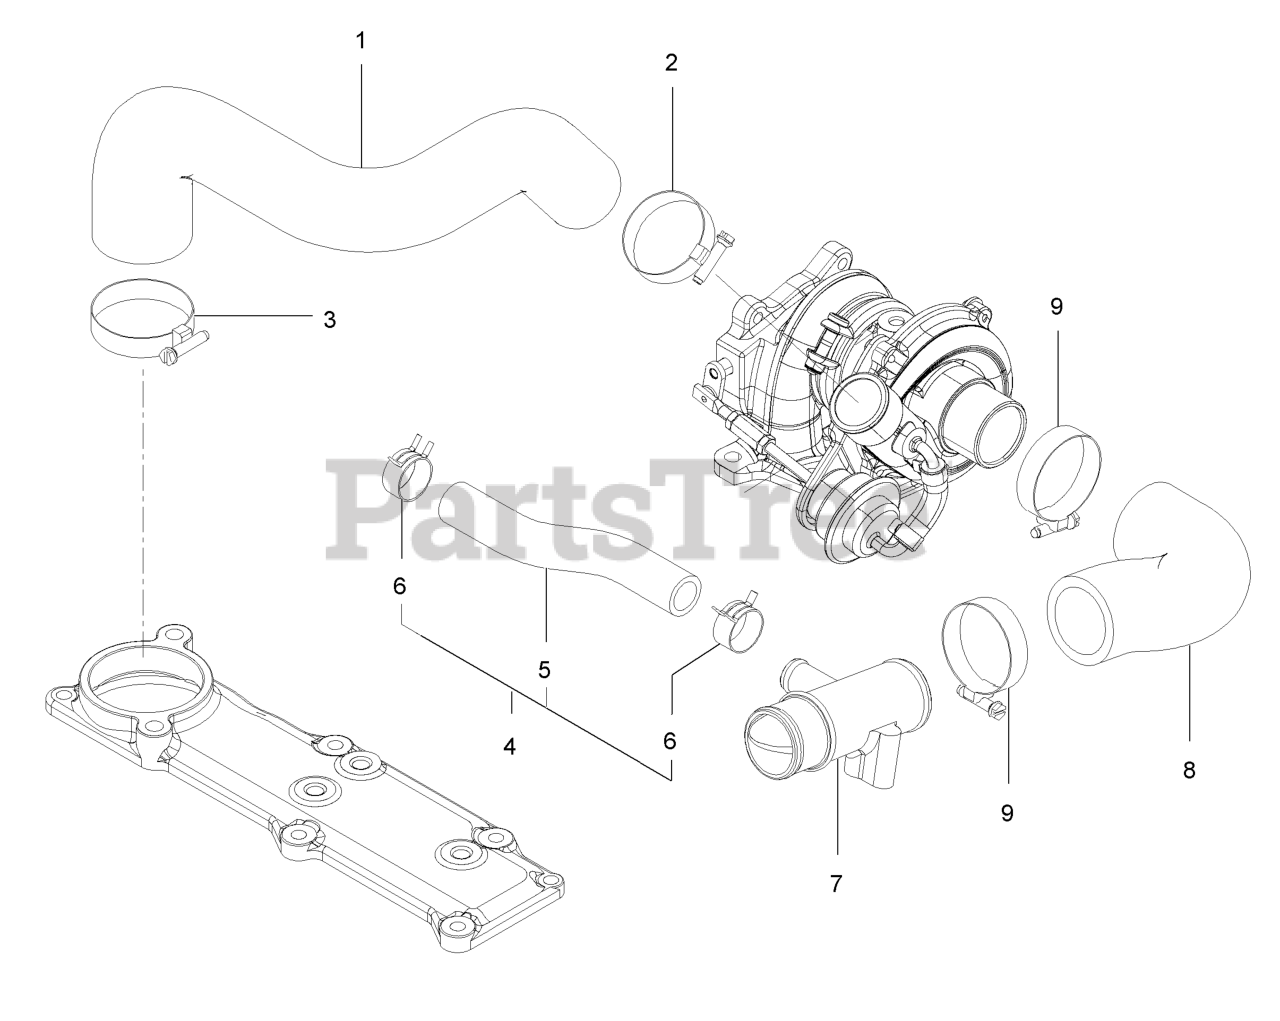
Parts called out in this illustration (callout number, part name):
1	Hose-Air Intake
2	Clamp-Hose
3	Clamp-Hose
4	Hose ASM-Breather
5	Hose-Breather
6	Clip-Hose
7	Joint-Breather
8	Hose-Air Intake
9	Clamp-Hose
